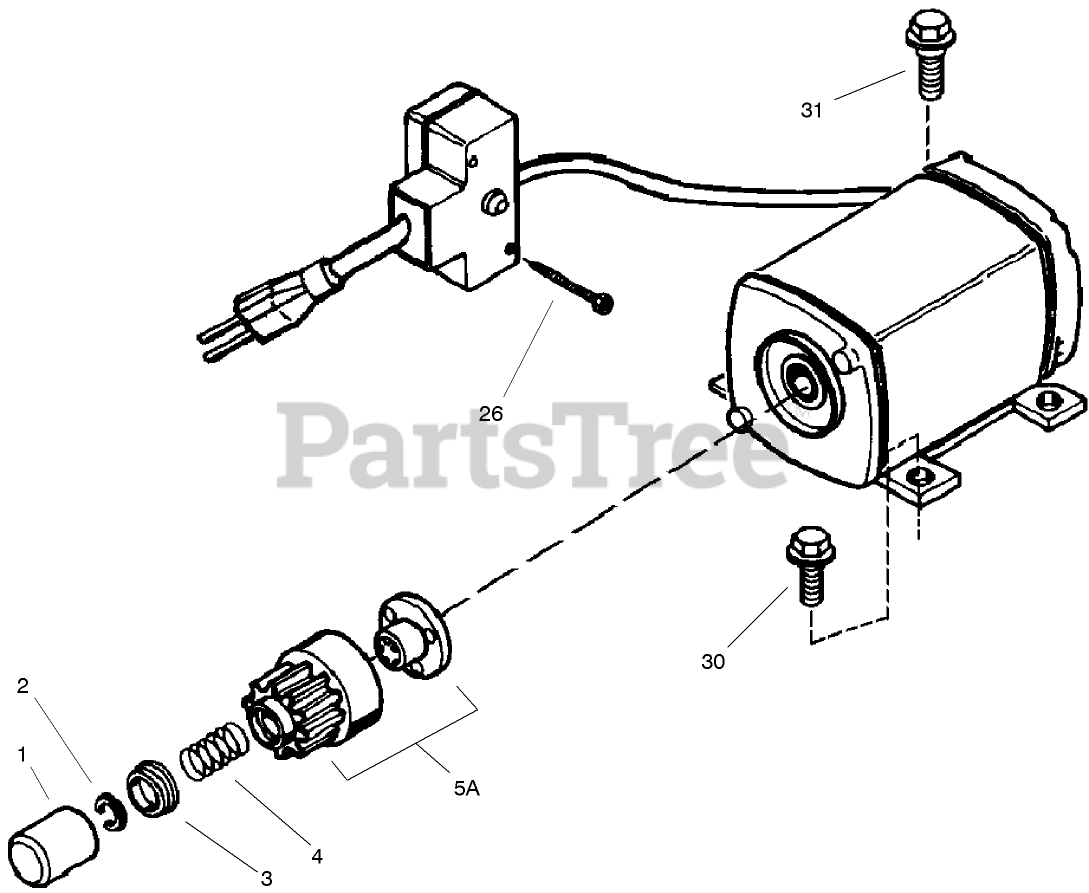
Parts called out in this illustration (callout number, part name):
1	Cover-Dust
2	Ring-Retainer
3	Retainer-Spring
4	Spring-Anti Drift
5A	Gear Nut (Incl. Ref.# 2)
26	Screw
26	Screw (12-16 x 5/8)
30	Screw
31	Screw (1/4-20x1/2)
